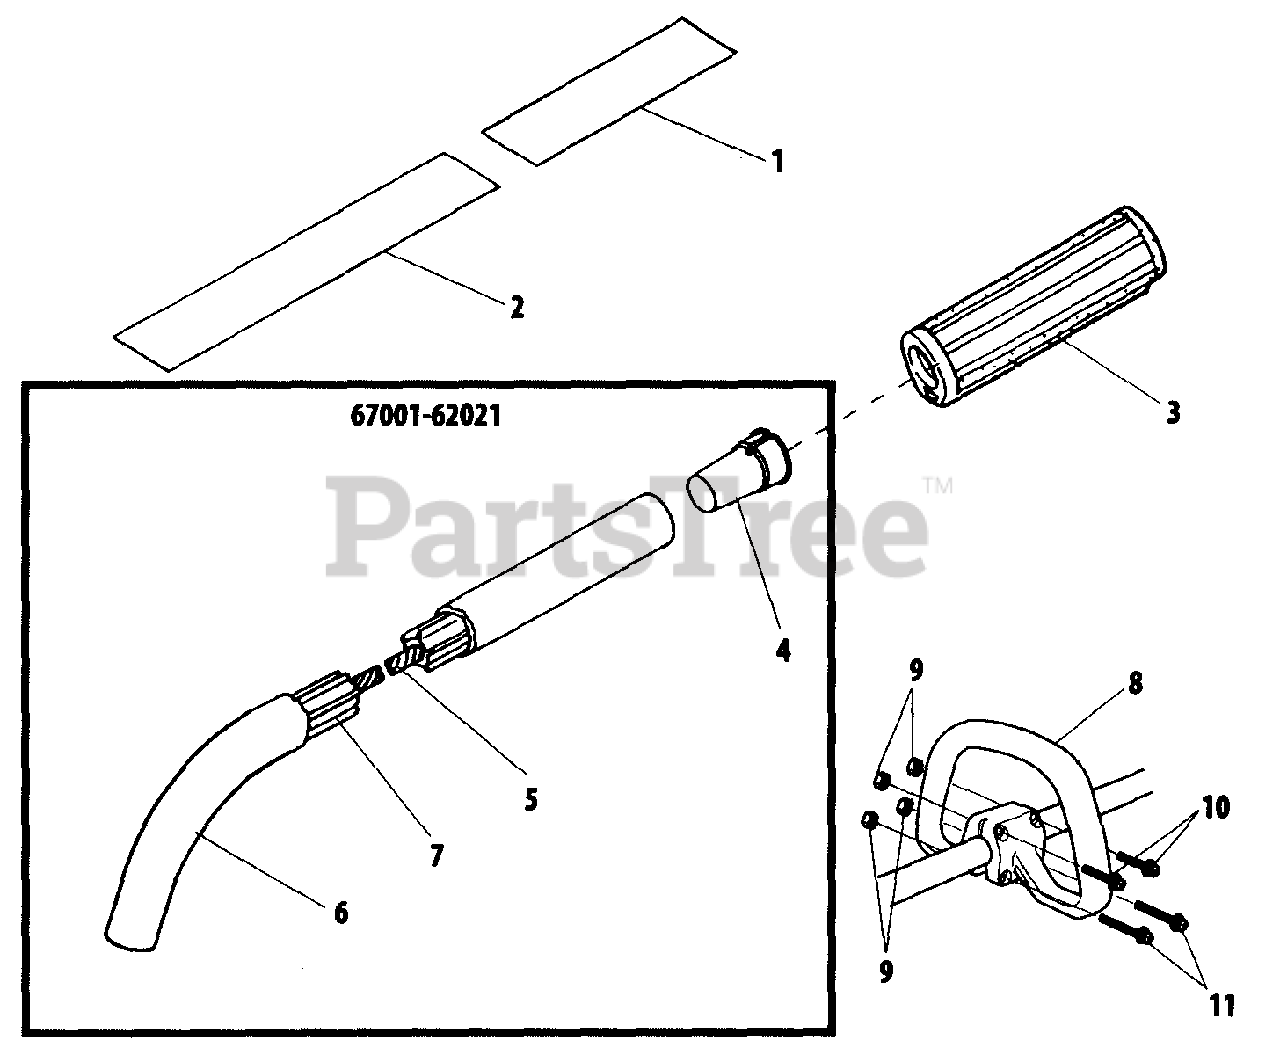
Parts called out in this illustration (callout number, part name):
1	LABEL, CAUTION
2	NAMEPLATE
3	GRIP
5	DRIVESHAFT - FLEXIBLE
6	PIPE, MAIN
7	LINER - FLEXIBLE
8	HANDLE, FRONT
9	NUT M5
10	SCREW M5×30
11	SCREW
67001-62021	MAIN PIPE ASSY
